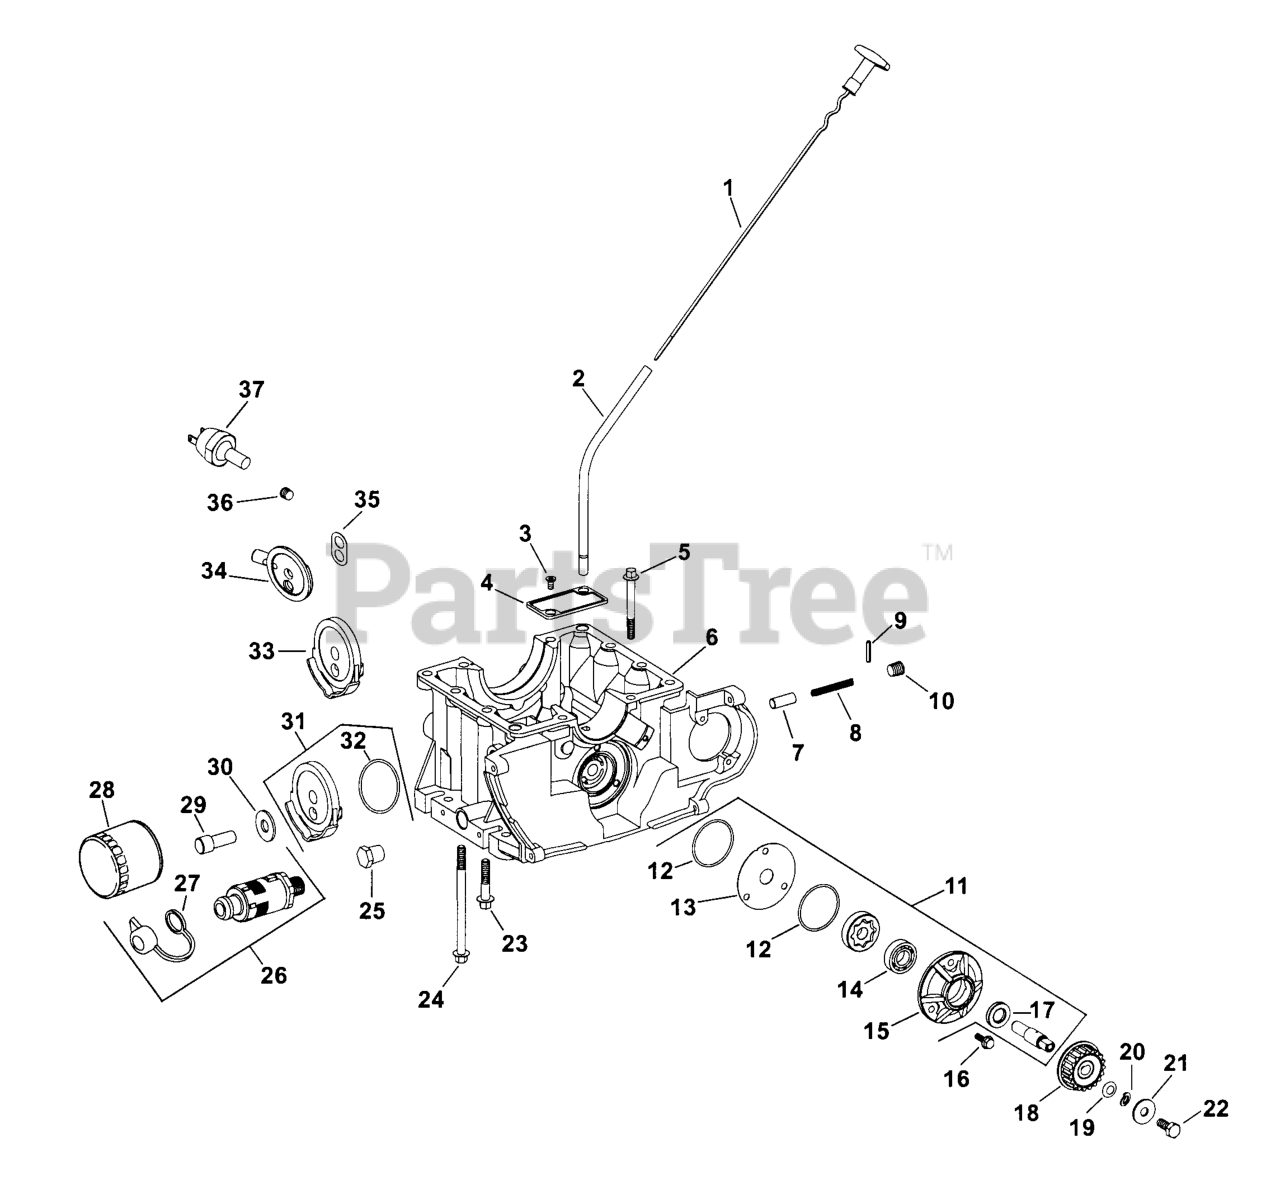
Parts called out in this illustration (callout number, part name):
1	DISC'D SEE EPB227
3	SCREW, TORX COUNTRSUNK HD
4	SCREEN, OIL PICK-UP - (#DSC)
5	SCREW, FLG M8X1.25X70
6	CRANKCASE-LOWER ASSEMBLY
7	VALVE, PISTON RELIEF
8	SPRING - DISCONTINUED
10	PLUG USE 25 139 64-S
11	PUMP ASSEMBLY, OIL - DISC.
12	O-RING - DISCONTINUED
13	PLATE, WEAR - DISCONTINUED
14	BEARING, BALL
16	SCREW, FLG M6x1.0x20
17	SEAL, OIL - DISCONTINUED
19	WASHER, SPRING 13 MM
20	WASHER, SPRING LOCK 1/4"
21	WASHER, FLAT 1/4"
22	SCREW, HEX HEAD MACHINE
23	SCREW, FLG M8X1.25X40 - (#M851040S)
24	SCREW, FLG M8X1.25X115
25	PLUG, HD PIPE 3/8"
28	OIL FILTER
29	NIPPLE, OIL FILTER
30	WASHER, FLAT - DISCONTINUED
31	KIT, PLASTIC FILTER ADAPTER - DISCONTINUED
32	O-RING - DISCONTINUED
37	KIT, OIL SENTRY(PRESSURE) - (#DSC)
